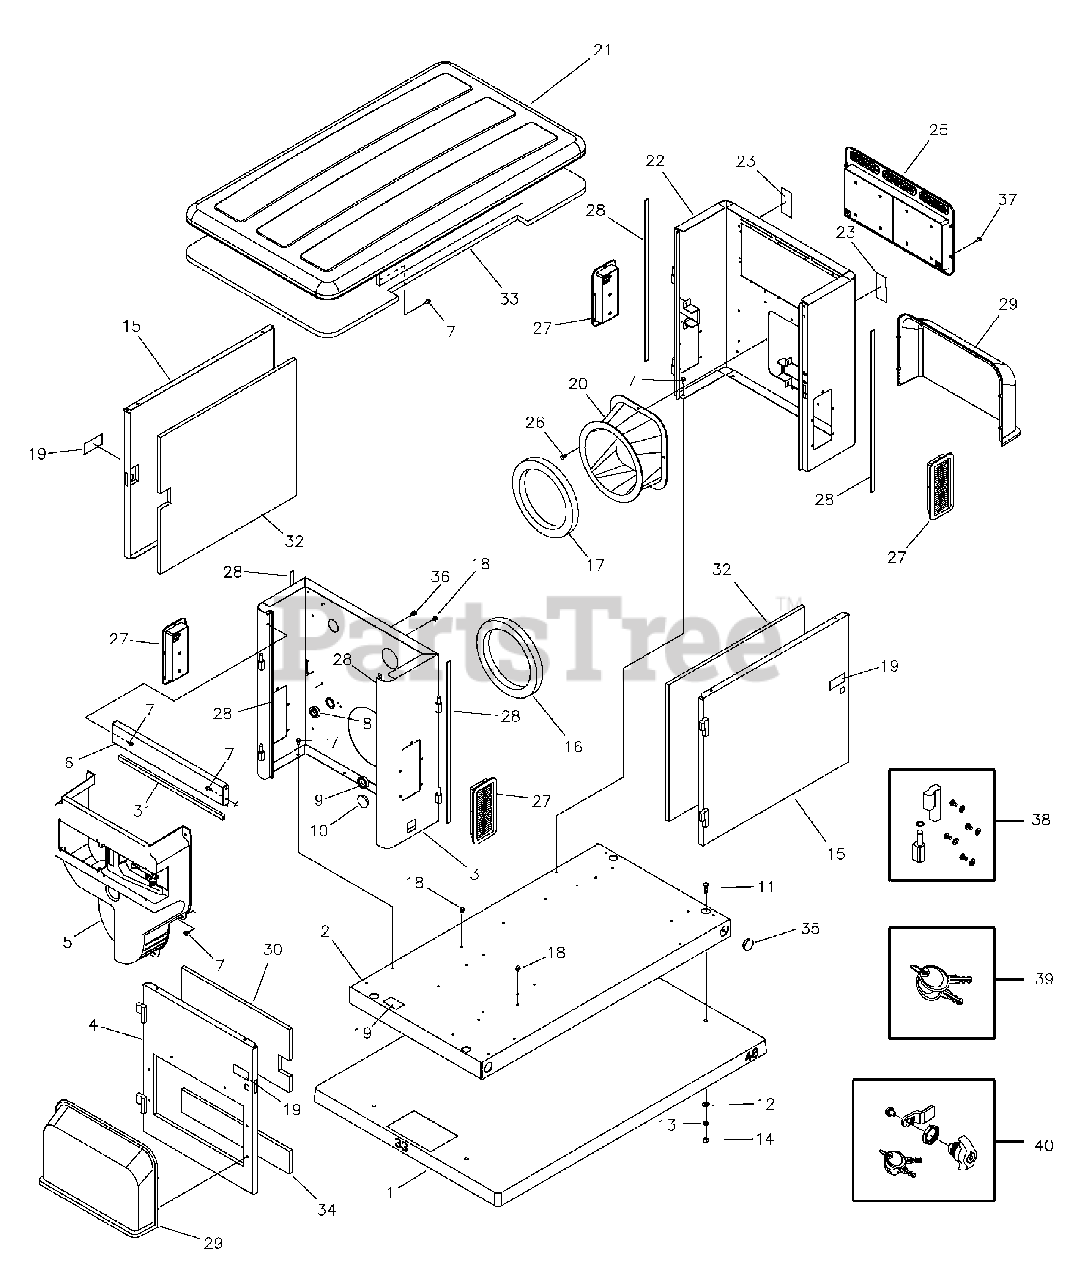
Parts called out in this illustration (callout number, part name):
2	BASE
3	BULKHEAD, Engine
7	BOLT
11	*CAPSCREW, Hex Head, 3/8-16 x 1
12	*WASHER, Flat, 3/8-M10
13	*WASHER, Lock, 3/8
14	*NUT, 3/8-16
20	ADAPTER, Engine
22	BULKHEAD, Alternator
29	COVER, Air Intake
37	SCREW
